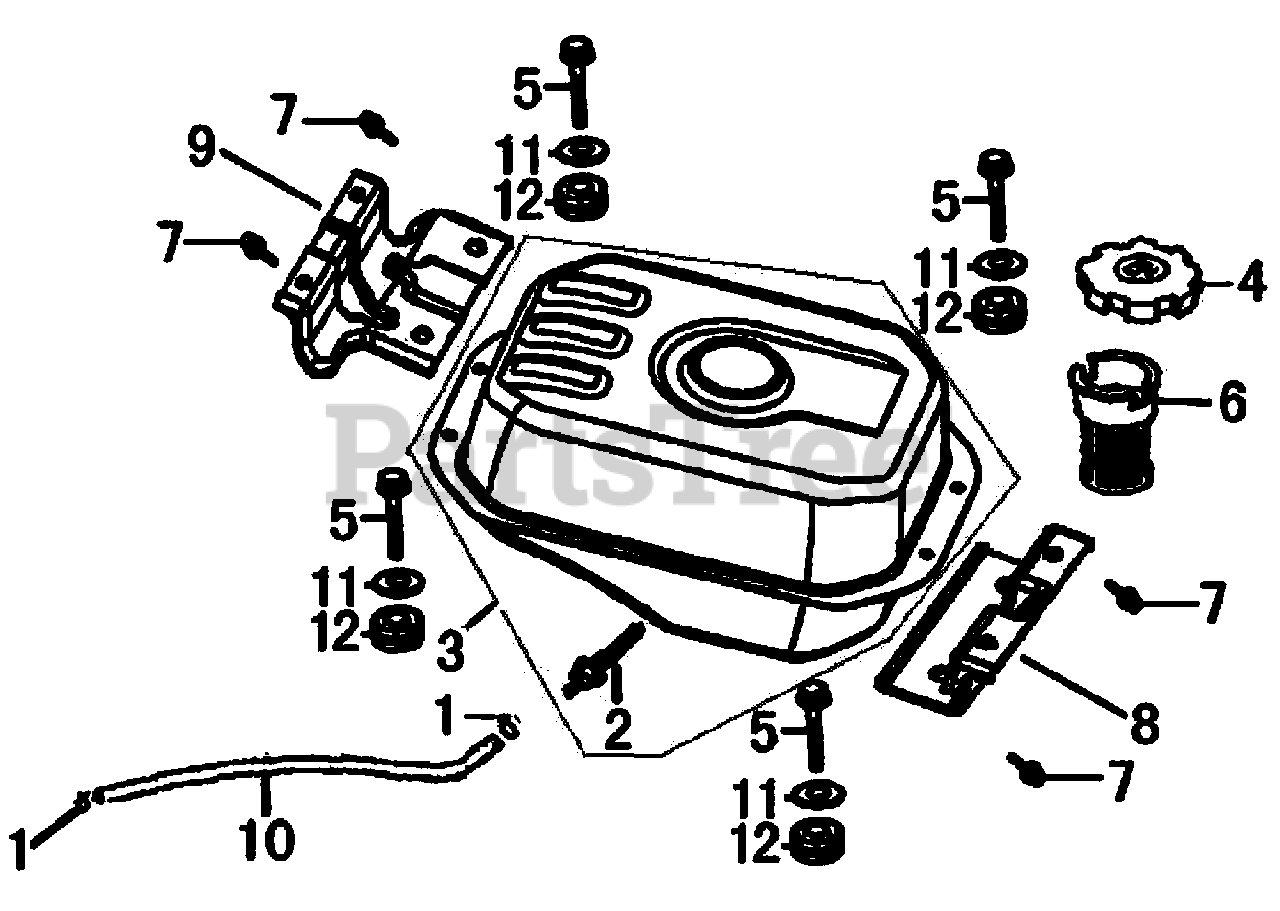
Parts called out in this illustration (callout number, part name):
1	LOOP, TUBE (CLAMP)
2	JOINT COMP., FUEL TANK
3	TANK COMP., FUEL
4	CAP COMP., FUEL FILLER
5	BOLT, GEXAGONAL
6	FILTER, FUEL
7	BOLT, FLANGE
8	HOLDER, FUEL TANK
9	HOLDER, FUEL TANK
10	TUBE, FUEL
11	WASHER, FLAT
